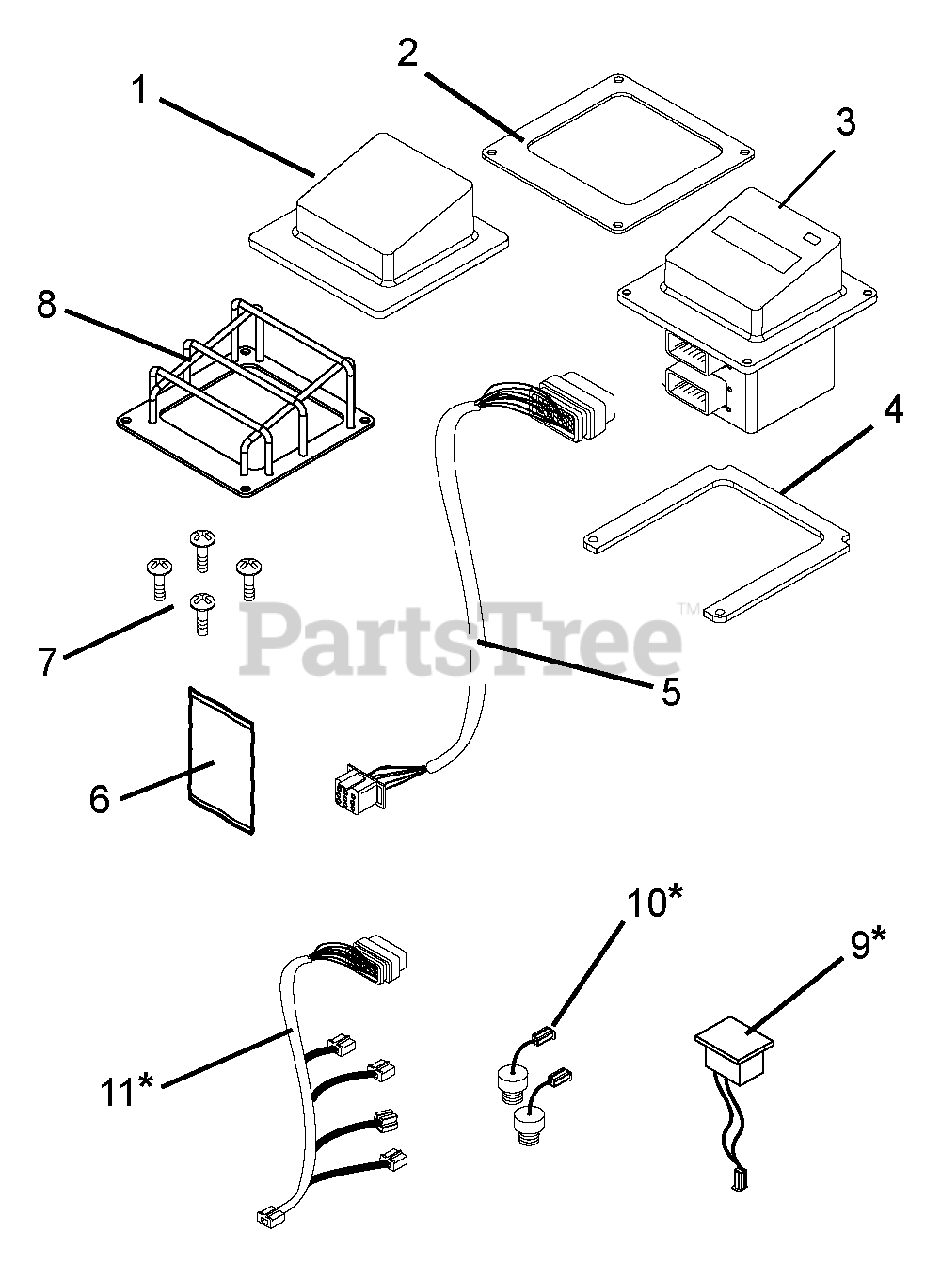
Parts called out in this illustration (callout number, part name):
1	GUARD, ELEMENT
2	GASKET-EYE Q
3	EYE Q ENHANCED
4	SPACER, ENCLOSURE MTG. (BTM)
5	HARNESS, EYE-Q
6	MANUAL-ENHANCED EYE Q
6	MANUAL, EYE-Q 2006 TRANSLATED
7	SCR-MCH 10-24X1.0 SL PAN BLACK
8	WMT, EYE-Q GUARD (BLACK)
9	KIT,EYE-Q ACCELEROMETER
10	KIT,EYE-Q TEMPERATURE
11	KIT,EYE-Q ACCESORY WIRE HRNS.
